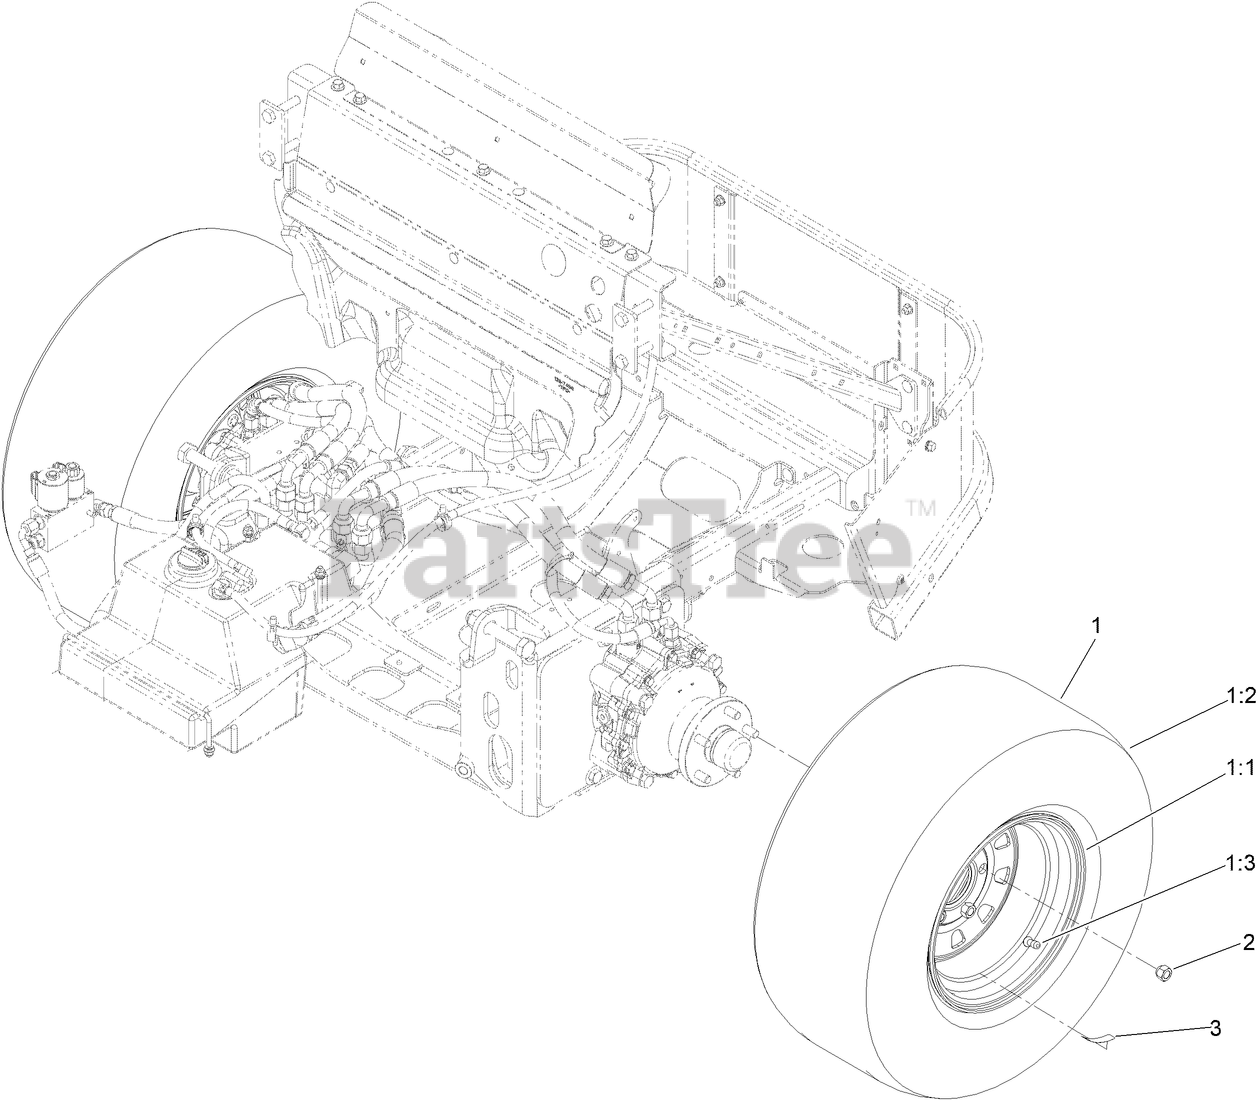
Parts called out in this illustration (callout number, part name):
1	TIRE ASM
2	NUT-LUG
3	DECAL-TORQUE, WHEEL NUT
